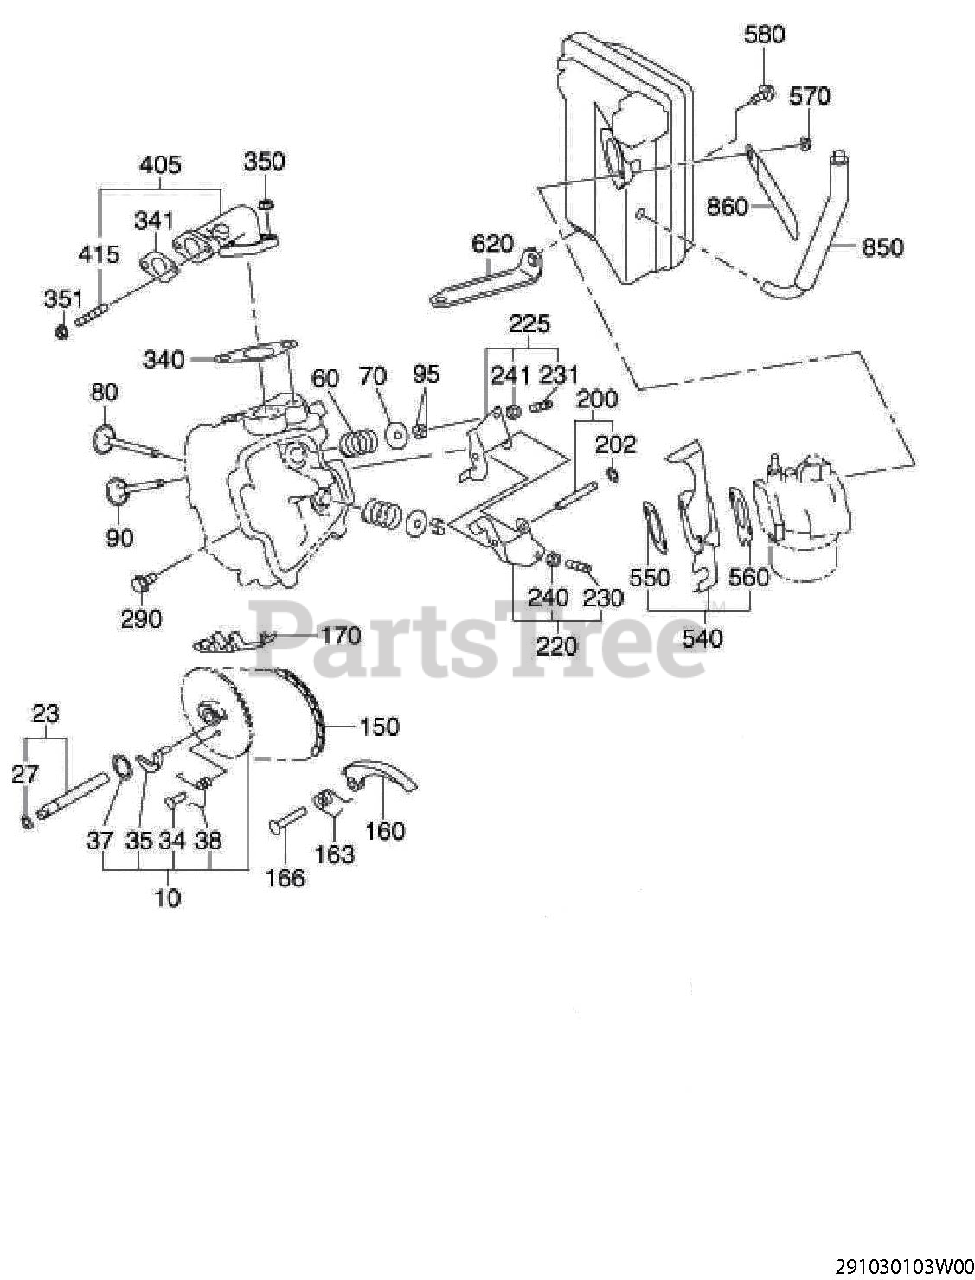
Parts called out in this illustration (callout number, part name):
10	CAM SHAFT CP
23	PIN(CAM SHAFT)
27	O RING
34	PIN(SPRING)
37	CLIP
38	RETURN SPRING
60	VALVE SPRING
70	SPRING RETAINER
80	INTAKE VALVE
90	EXHAUST VALVE
150	TIMING CHAIN CP
163	SPRING(TENTIONER)
166	PIN(TENTIONER)
200	PIN(ROCKER) CP
202	CLIP
220	ROCKER ARM(IN) AY
225	ROCKER ARM(EX) AY
230	ADJUST SCREW
231	ADJUST SCREW
240	NUT
241	NUT
290	FLANGE BOLT
340	GASKET(MUFFLER)
341	GASKET CP(EXHAUST)
350	FLANGE NUT
351	FLANGE NUT
405	EXHAUST PIPE CP
415	STUD
540	INSULATOR CP
550	GASKET2(INSULATOR)
560	GASKET1(INSULATOR)
570	FLANGE NUT
580	FLANGE BOLT
620	BRACKET(A/C) CP
850	RUBBER PIPE AY
860	CLAMP
